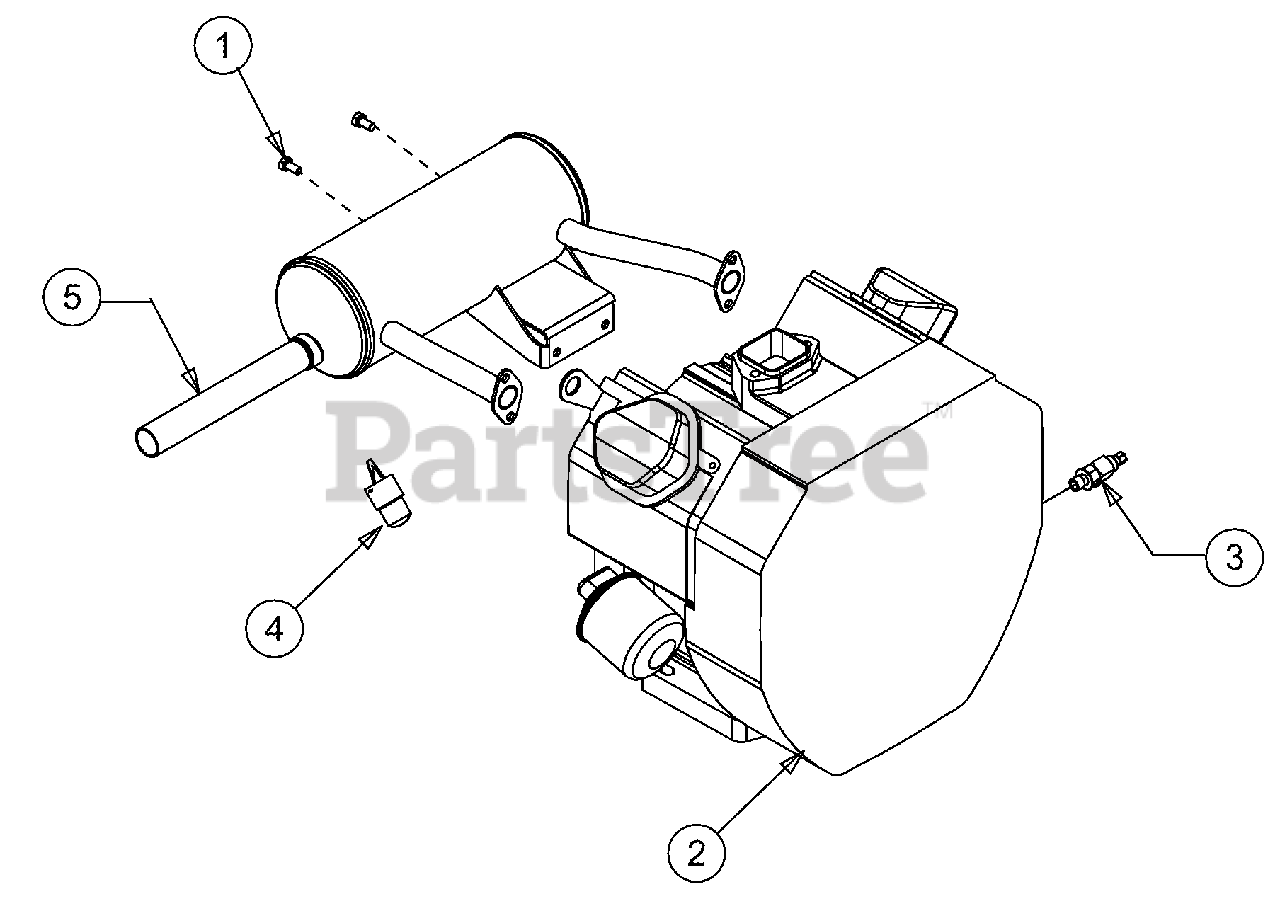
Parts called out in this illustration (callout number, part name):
1	Screw, M8
2	Engine, Honda GX618K1
3	Valve, Oil Drain
4	Spark Arrestor
5	Muffler, Honda GX620
